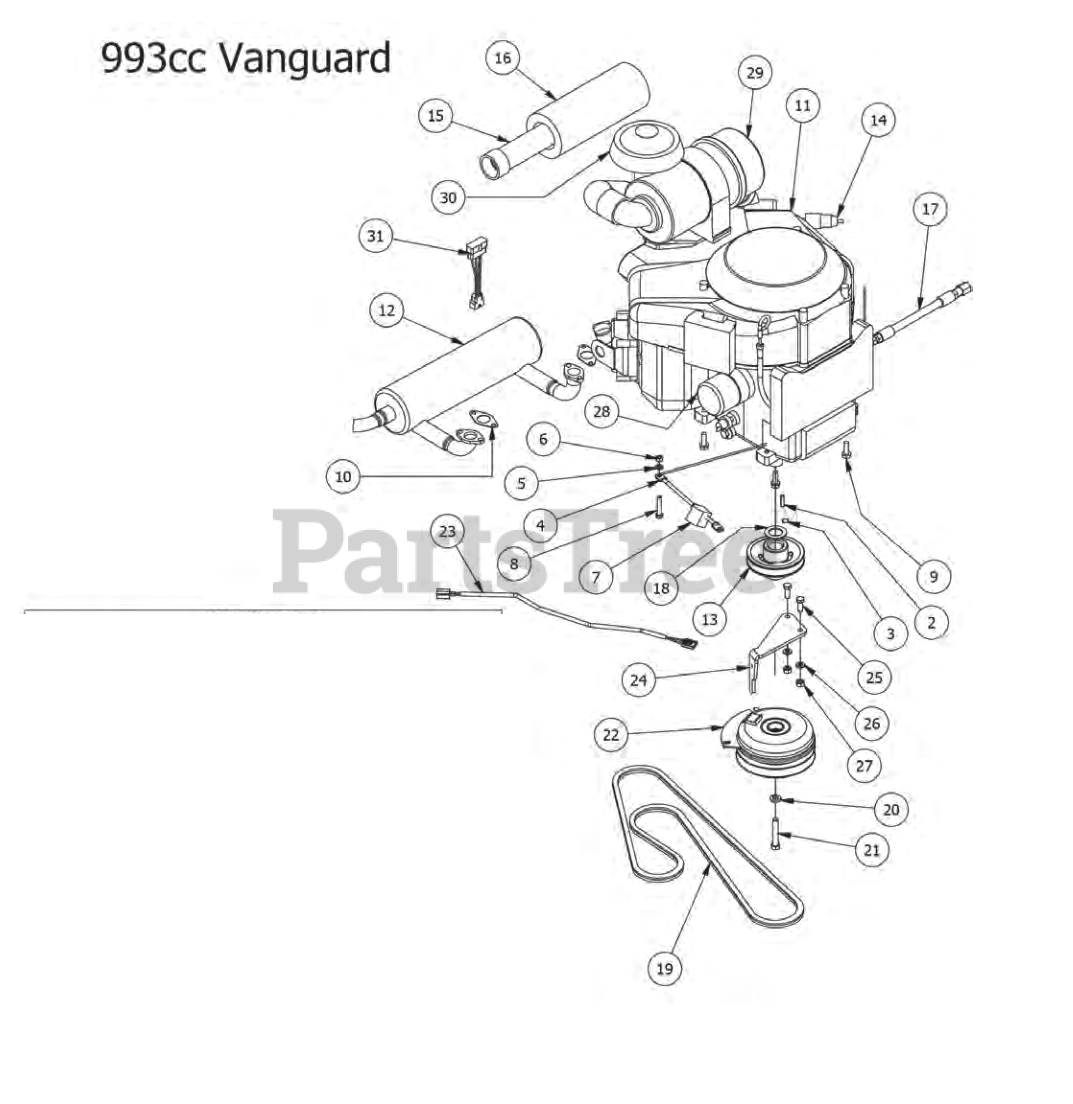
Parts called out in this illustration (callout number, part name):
2	1/4" x 1" Key
3	5/16 Set Screw
4	Starter to chassis cable
5	5/16" Lock Washer
7	Black Boot For ground cable
8	5/16" x 1 3/4" Hex Bolt
9	3/8 x 1 1/8 bolt
10	Exhaust Gasket for 23 Vanguard
11	993cc Briggs Vanguard Engine
12	32Hp Vanguard Exhaust
13	4 3/4 Motor Pulley
14	Universal inline Fuel Filter
15	Canister Air Filter- Inner
16	Canister Air Filter- Outer
17	14 mm Oil drain Hose 993cc Vanguard
18	1 1/8" Flat Spacer
20	7/16" Lock Washer
21	7/16" x 2 1/2" Hex Bolt
22	Clutch Assembly
23	Clutch Pigtail
24	PTO Engager Holder
25	3/8" x 1" Hex Bolt
26	3/8" Lock Washer
27	3/8" Hex Nut
28	Briggs Oil Filter
29	Complete Canister
30	Rain Cap Fits all Canisters
31	Harness Adaptor - 933cc Vanguard
